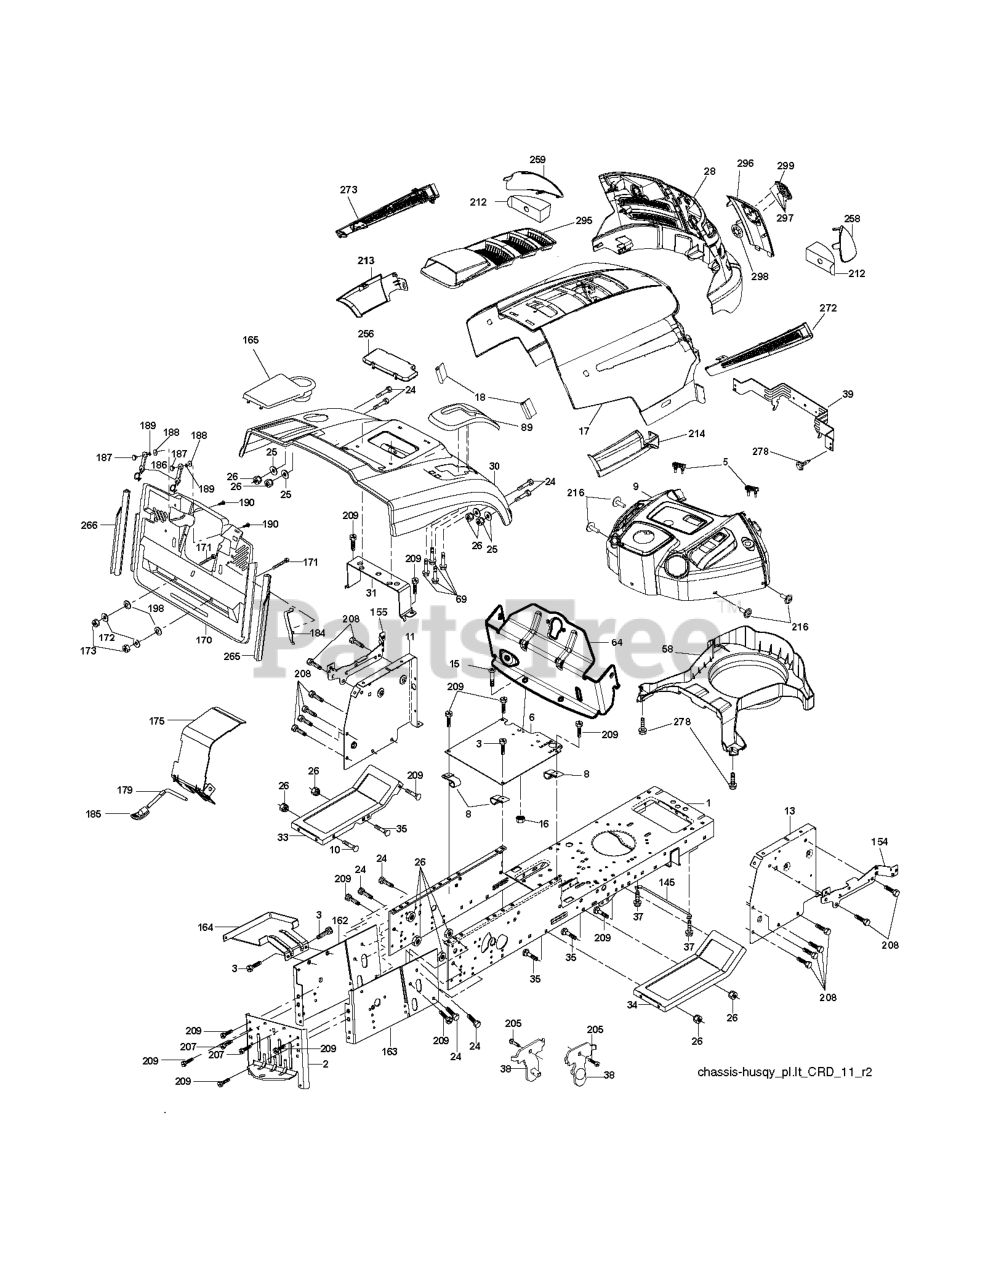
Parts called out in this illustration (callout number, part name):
2	DRAWBAR
3	SCREW 3/8-16X3/4
5	BUMPER DASH
6	PLATE
8	CLIP,INSULATOR
10	BOLT D
11	PANEL.DASH.LH.LTX
13	PANEL ASM, DASH RH
15	Screw, Machine, Truss Head 5/16-18 UNC x 3/4
16	NUT
17	HOOD
18	BUMPER.HOOD.TEX.HUSQVARNA
25	WASHER
26	NUT
28	RP GRILLE/LENS ASM.
30	CONSOLE.CRD.AUTO.GRY
31	BRACKET SUPPORT FENDER
33	FOOTREST PNT LH
34	FOOTREST PNT RH
37	Screw 5/16-18 x 1/2 Hex, Self Tapping 5/16-18 x 1/2
38	BRACKET ASM PIVOT MOWER REAR
39	BRACKET PIVOT
69	SCREW.HI-LO.CONSOLE
89	CONSOLE.CRD.AUTO.GREY.2005
145	ROD.PIVOT.HOOD
162	BRACKET
163	BRACKET EXTEN CHASSIS RH CRD
165	RP.COVER.BATTERY.CRD.GREY
172	WASHER
175	DOOR TRAP
179	ROD PIVOT FBI
184	BRACKET.ACTUATOR.BAGGER.SRD
186	LATCH ASSY
187	WELDNUT
189	LOCKWASHER #10
190	SCREW
207	SCREW, 5/16-18 X 1/2
208	SCREW 3/8-16X1/2
209	SCREW, 3/8-16X3/4
212	INSERT REFLECTIVE
213	SKIRT SIDE LH
214	SKIRT SIDE RH
216	SCREW HEXWSHR 1/4-20X3/4
256	COVER FENDER CRD
258	LENS.HUSQVARNA LT.RH
259	LENS.HUSQVARNA LT.RH
265	SEALING
266	SEALING
278	SCREW
295	VENT TOP HOOD
296	TRIM
297	CLIP.RETAINER.TINNER.
298	NUT PUSH M
299	RP LOGO
